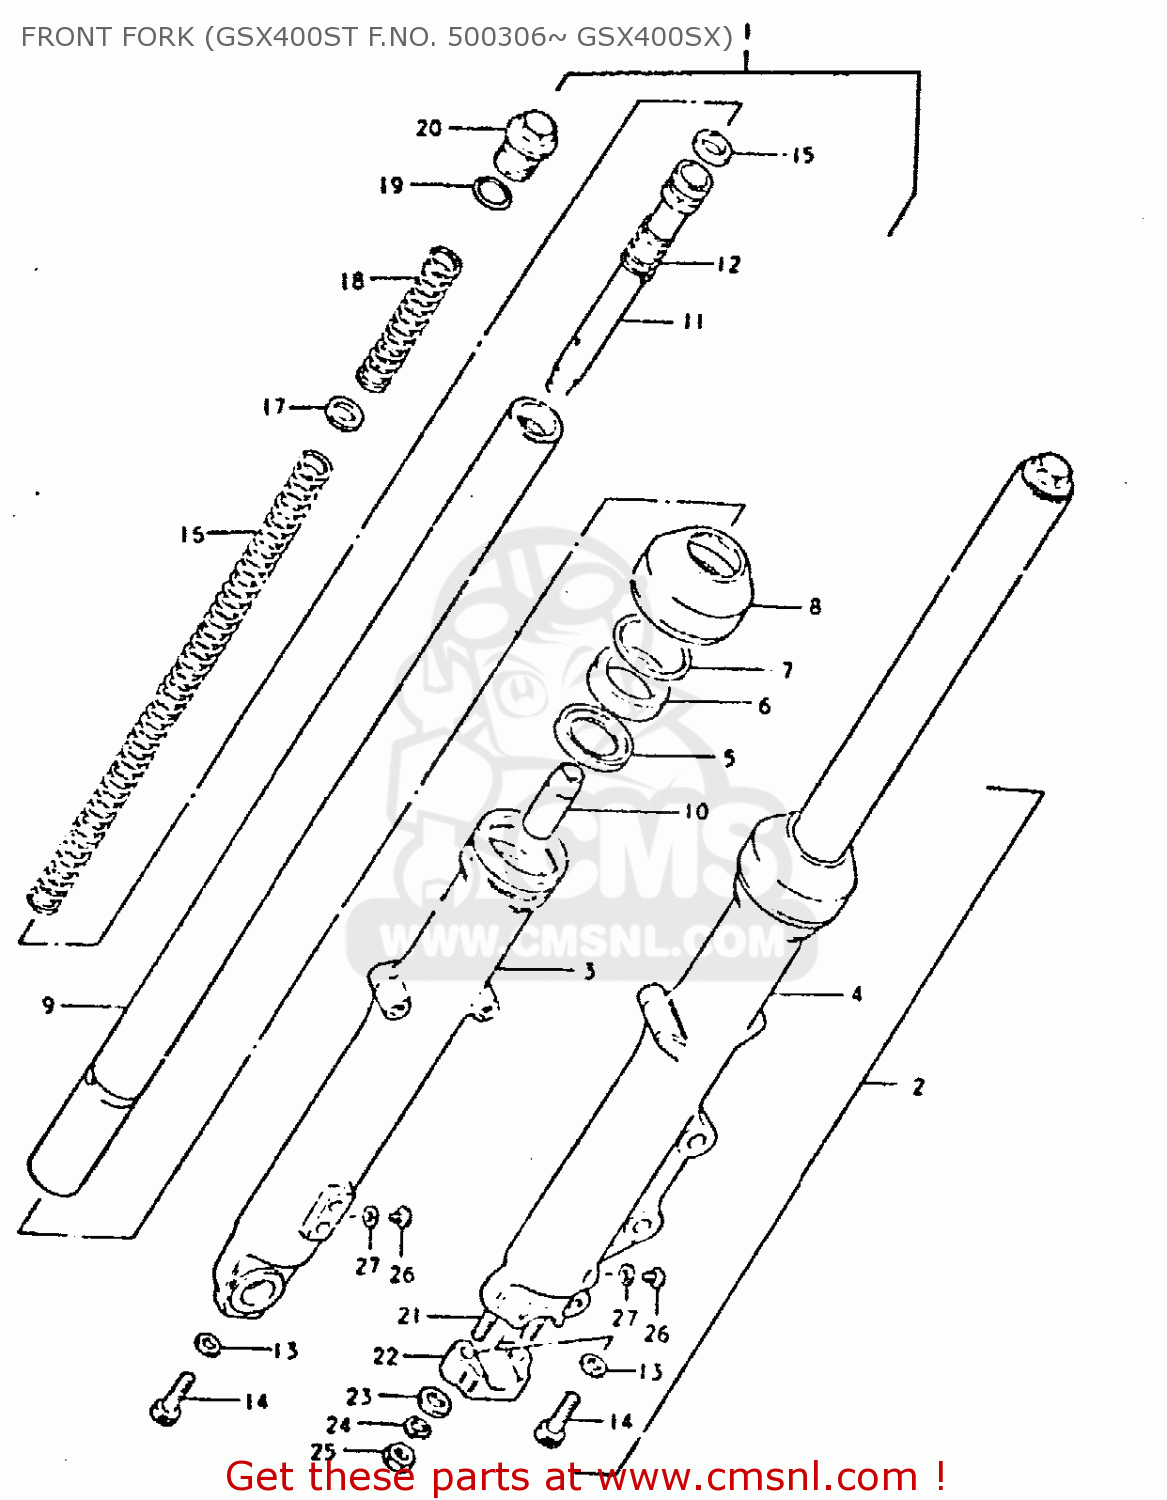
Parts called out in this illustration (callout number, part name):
1	DUMPER ASSY, RH
2	DUMPER ASSY, LH
3	TUBE,FORK,OUTER,RIGHT
4	TUBE,FORK,LEFT,OUTER
5	SPACER,OIL SEAL
6	OIL SEAL,FRONT FORK
7	CIRCLIP,FORK OIL SEAL
8	BOOT
9	TUBE,INNER
10	PIECE,OIL LOCK
11	CYLINDER,FRONT FORK
12	SPRING,REBOUND
13	GASKET (NAS)
14	BOLT(8X27)
15	RING,PISTON
16	SPRING
17	SEAT,SPRING
18	SPRING,FRONT FORK
19	O RING
20	BOLT
21	STUD 8X25
22	HOLDER,AXLE
23	WASHER
24	LOCK WASHER
25	NUT (8MM)
26	SCREW 4X6
27	GASKET (NAS)
